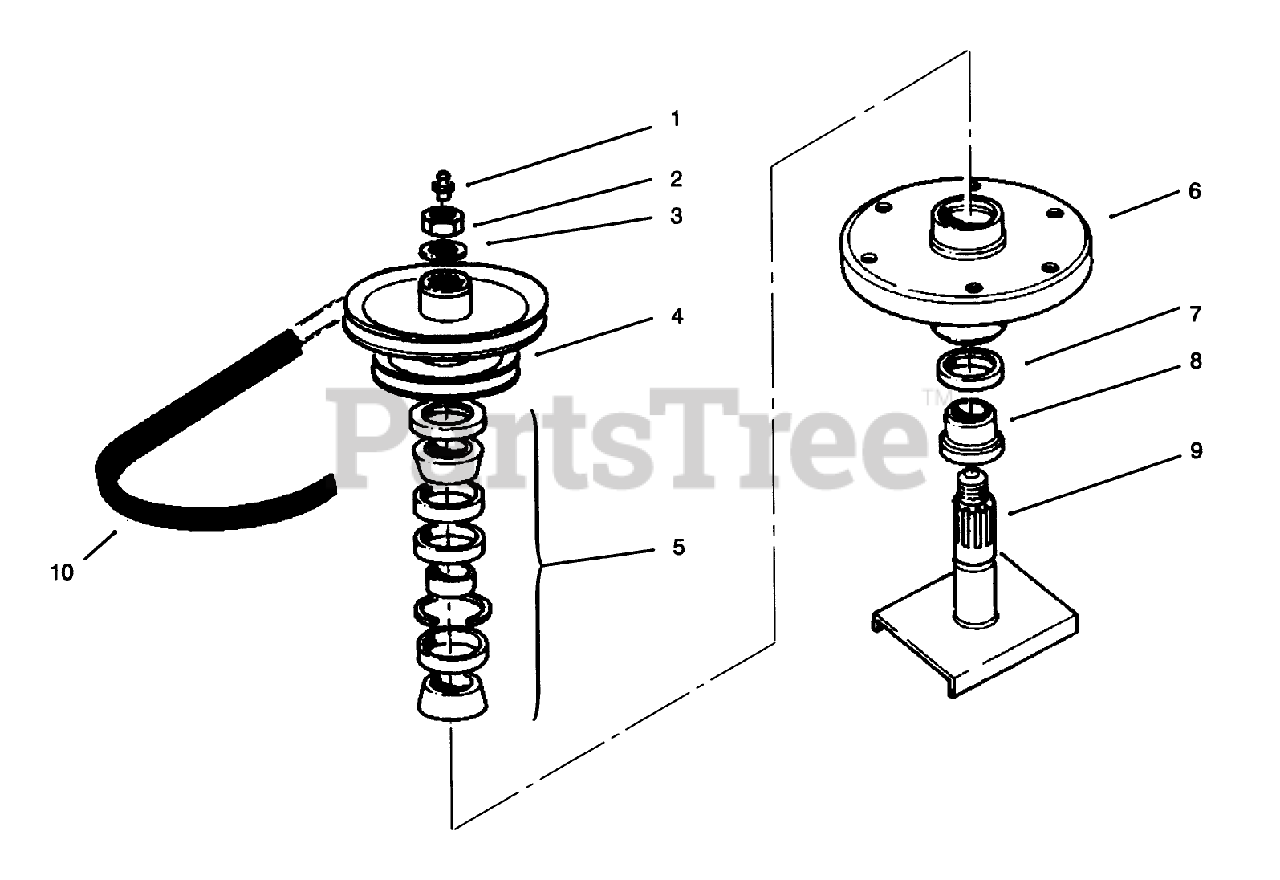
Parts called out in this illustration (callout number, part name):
1	FITTING-GREASE
2	NUT-HEX
3	WASHER
4	PULLEY AND HUB ASM
5	BEARING ASM
6	HOUSING-SPINDLE
7	SEAL-OIL
8	SPACER
9	Shaft-Spindle
10	V-BELT
